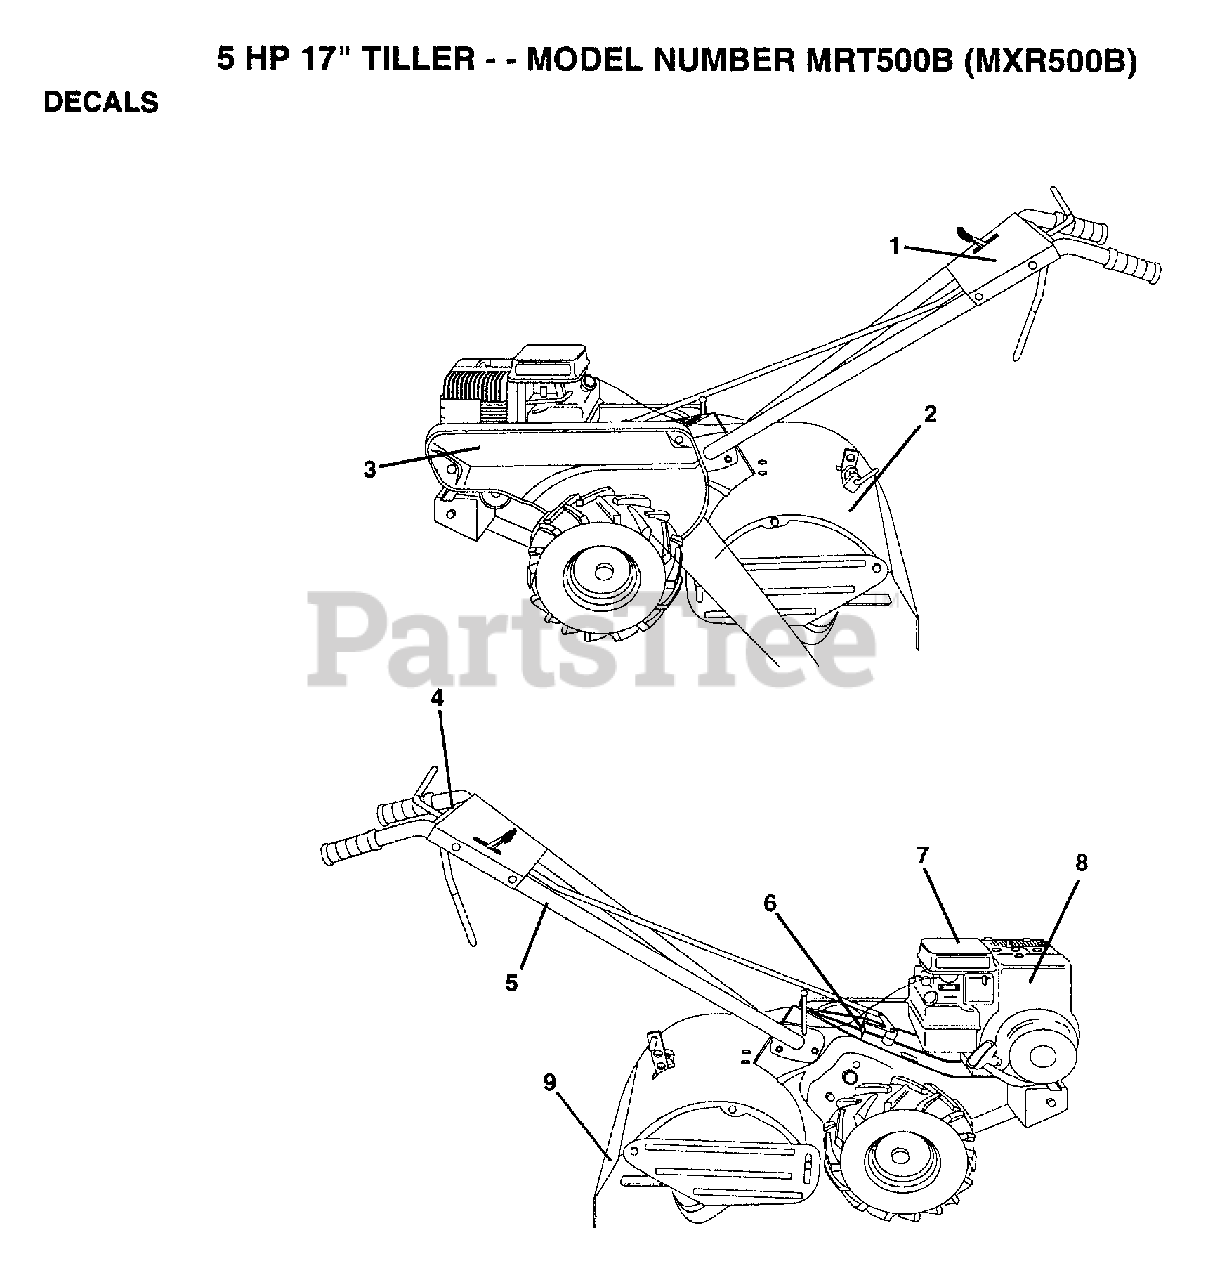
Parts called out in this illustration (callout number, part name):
1	DECAL CNTRL PANEL
2	DECAL SHIELD TINE
3	DECAL GUARD BELT
5	DECAL TI
7	DECAL TI
